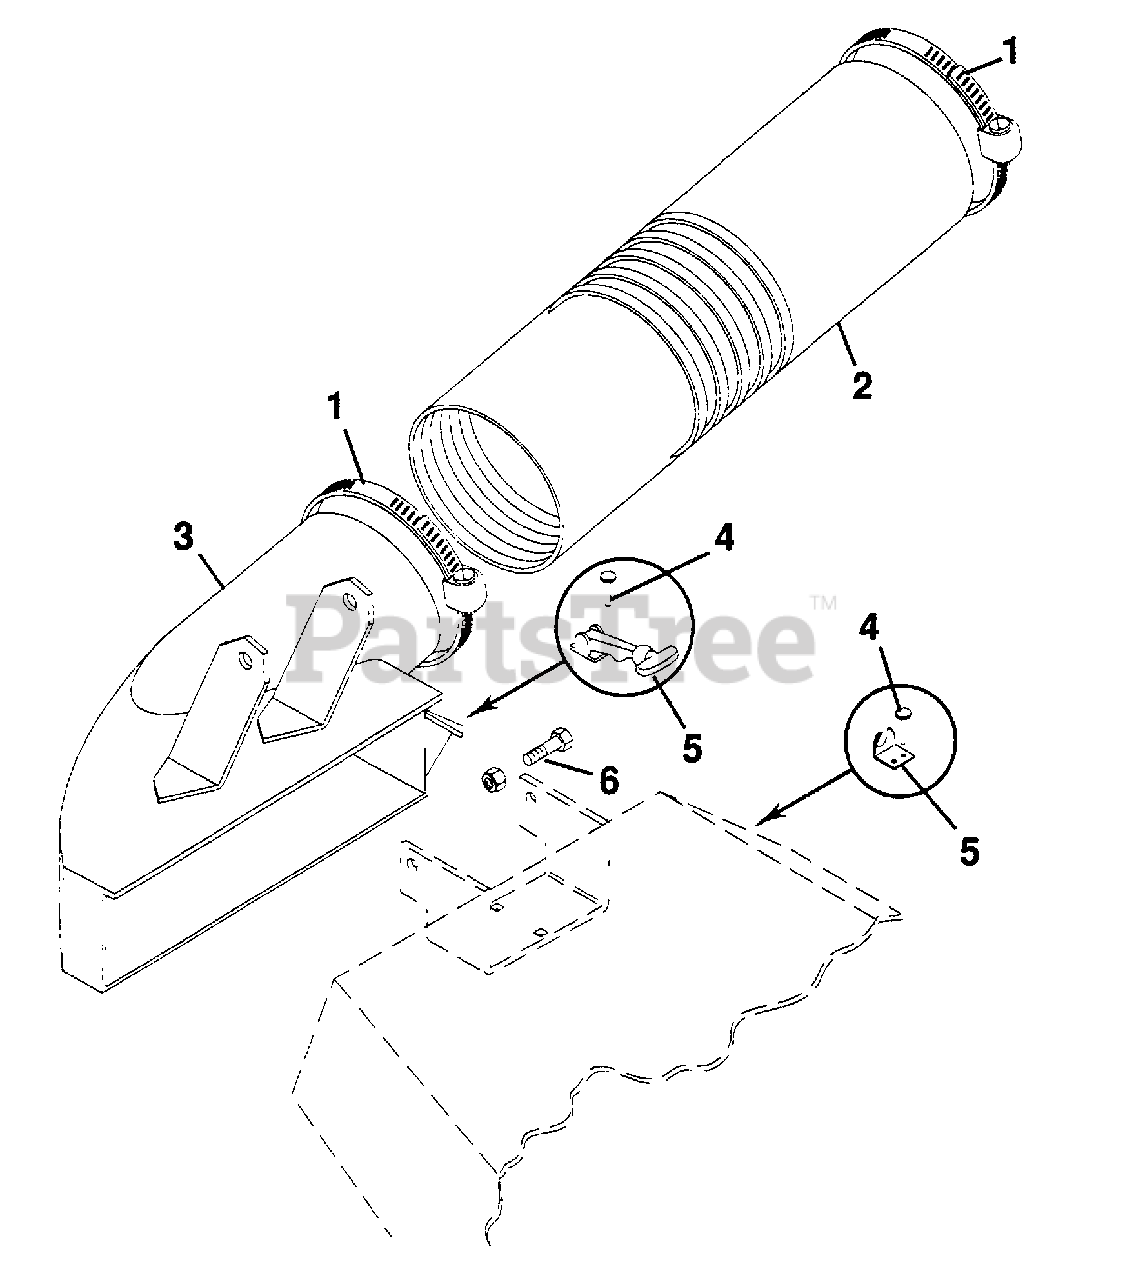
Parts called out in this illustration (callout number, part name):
1	Clamp
2	Hose, Mower to Blower
3	Weldment, 60" Boot
4	Rivet, Dome Head
5	Latch, Flexible Draw
6	Bolt, Hex 3/8-16x1.50
